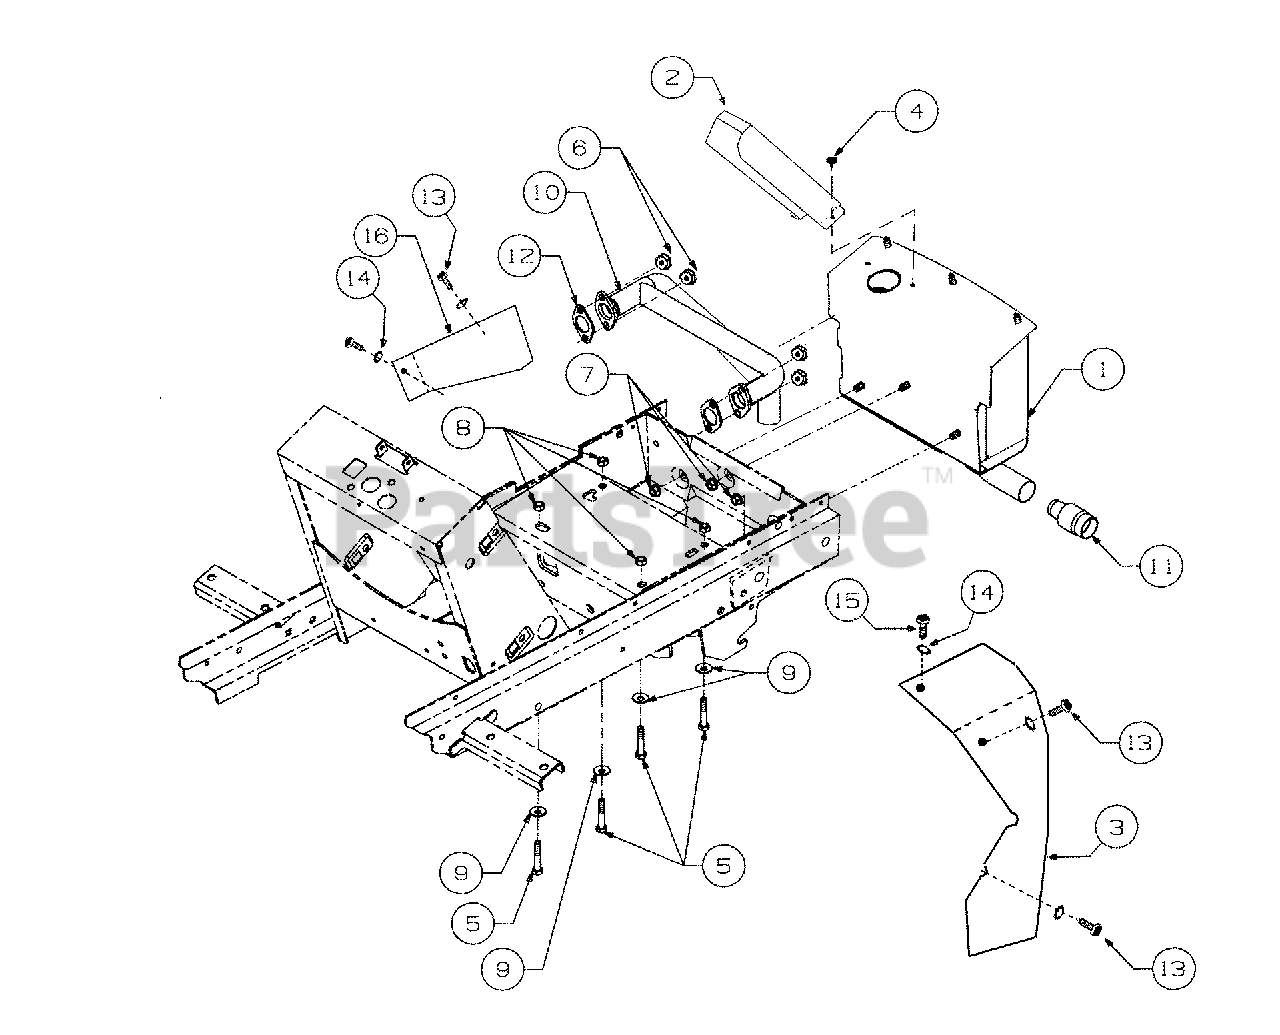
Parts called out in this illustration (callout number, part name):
1	Muffler Assembly
2	Sheild, Muffler Tube
5	Bolt, Eng Mount, 3/8-24 x 1.75 GR5
6	Nut, Hex Flange
7	Nut, Hex Flange Lock, 5/16-18
8	Nut, Hex Lock, 3/8-24
9	Washer, Bell, .380 x .88 x .062
10	Tube, Exhaust
11	Arrestor, Spark
12	Gasket, Exhaust
13	Screw, Hex Cap, M6 x 1 x 10
14	Washer, Flat, .281 x .5 x .06
15	Screw, Truss Hd Tapp, #10 x .5
